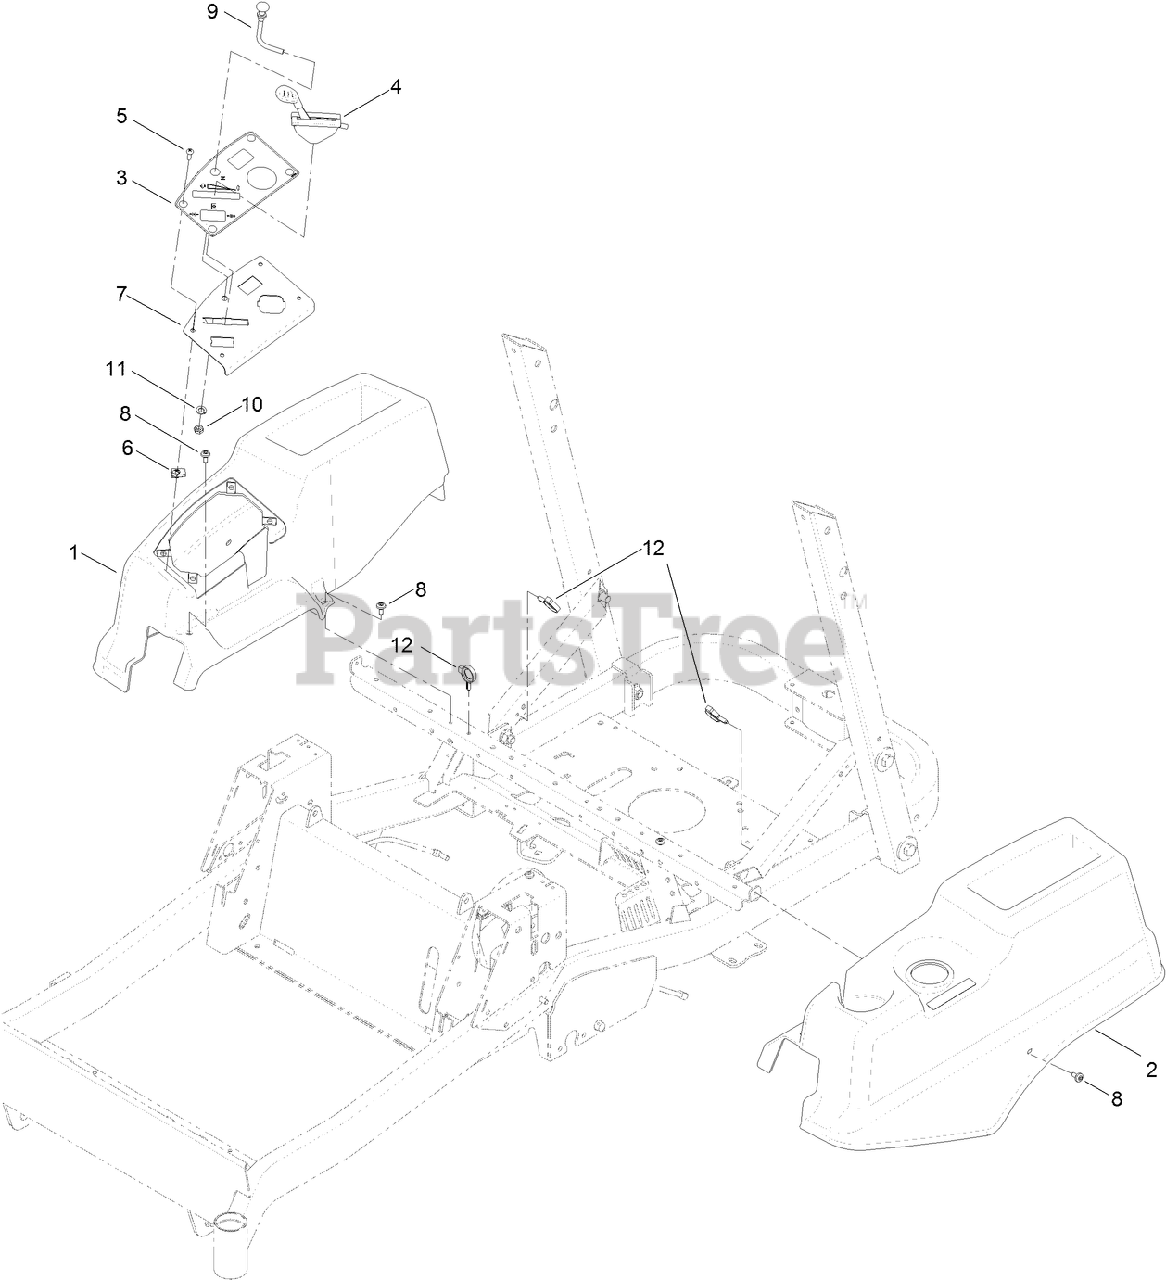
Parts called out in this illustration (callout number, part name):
1	POD-RH
2	POD-LH
3	DECAL-PANEL, CONTROL
4	CABLE-THROTTLE
5	SCREW-PRH
7	PANEL-CONTROL
8	SCREW-SHOULDER
9	CABLE-CHOKE
10	WASHER-LOCK
11	NUT-HJ
12	CLAMP-HOSE
